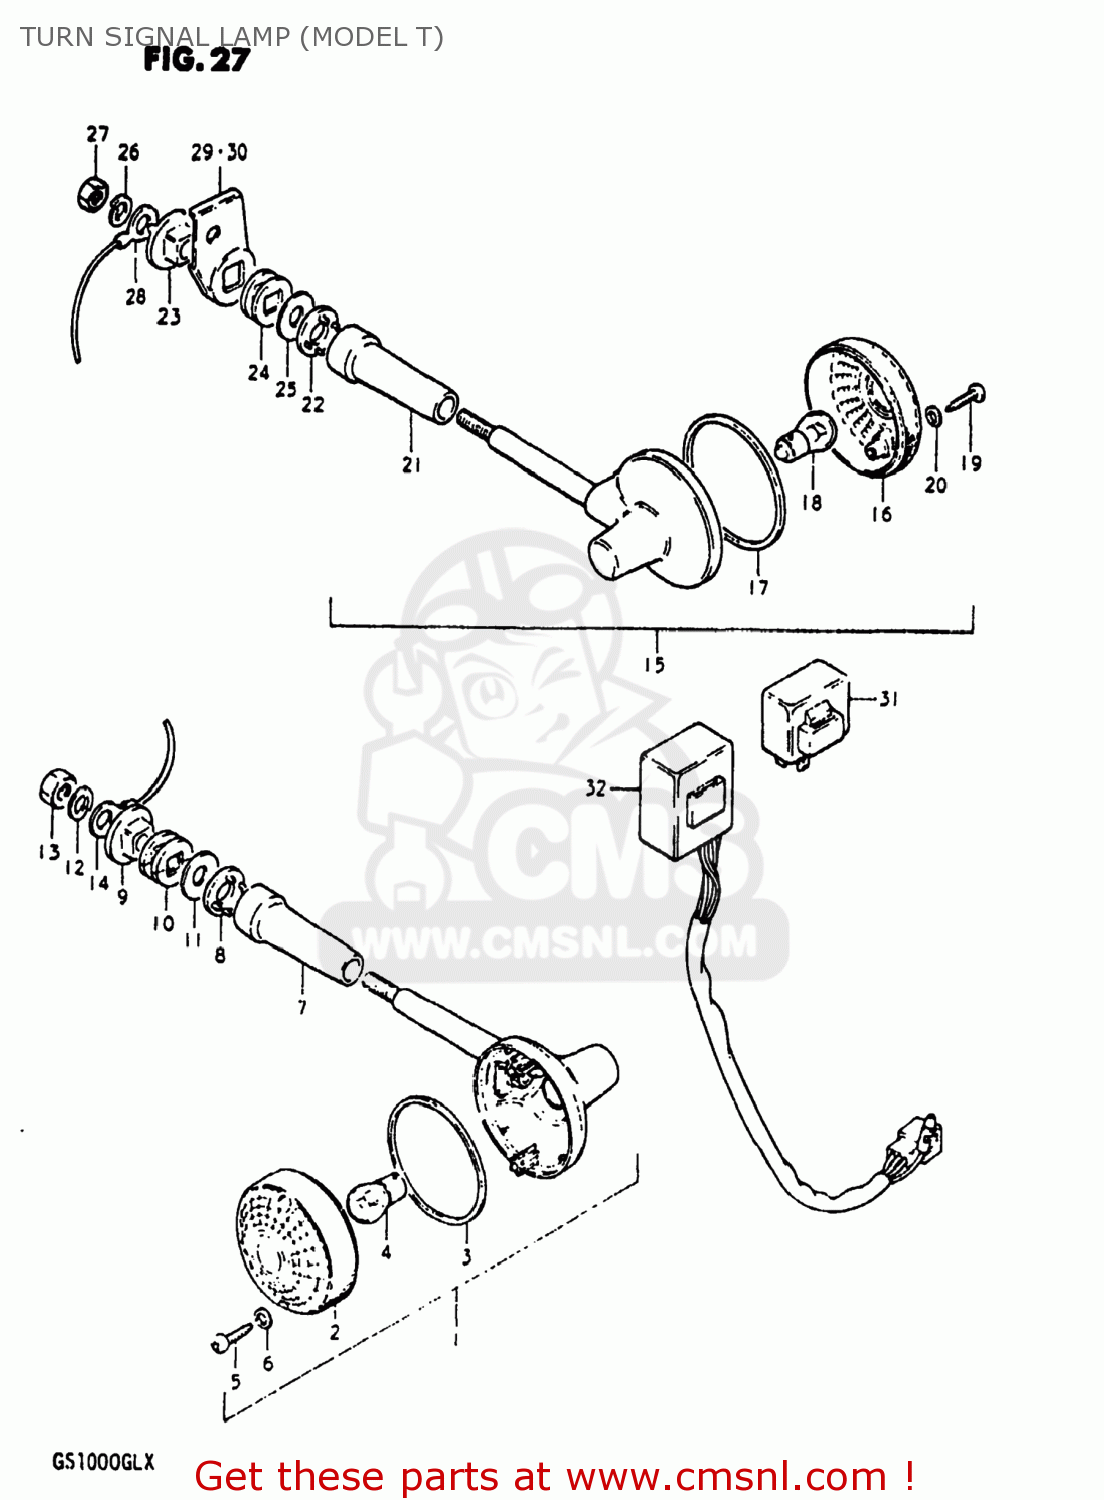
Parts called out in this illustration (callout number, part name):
1	LAMP ASSEMBLY,REAR TURN SIGNAL
2	LENS
3	GASKET (NAS)
4	BULB(12V23W,STANLEY,A4577A)
5	SCREW
6	GASKET (NAS)
7	COVER,STAY
8	SPACER
9	SPACER,TURN SIGNAL LAMP
10	CUSHION
11	WASHER (10.5X30X2.3)
12	LOCK WASHER
13	NUT
14	WIRE
15	LAMP ASSEMBLY,REAR TURN SIGNAL
16	LENS
17	GASKET (NAS)
18	BULB(12V23W,STANLEY,A4577A)
19	SCREW
20	GASKET (NAS)
21	COVER,STAY
22	SPACER
23	SPACER,TURN SIGNAL LAMP
24	CUSHION
25	WASHER (10.5X30X2.3)
26	LOCK WASHER
27	NUT
28	WIRE
29	BRACKET,RR TURNSIGNAL LAMP,R
30	BRACKET,RR TURNSIGNAL LAMP,L
31	RELAY ASSY,TURNSIGNAL
32	UNIT,TURN SIGNAL CONTROL
